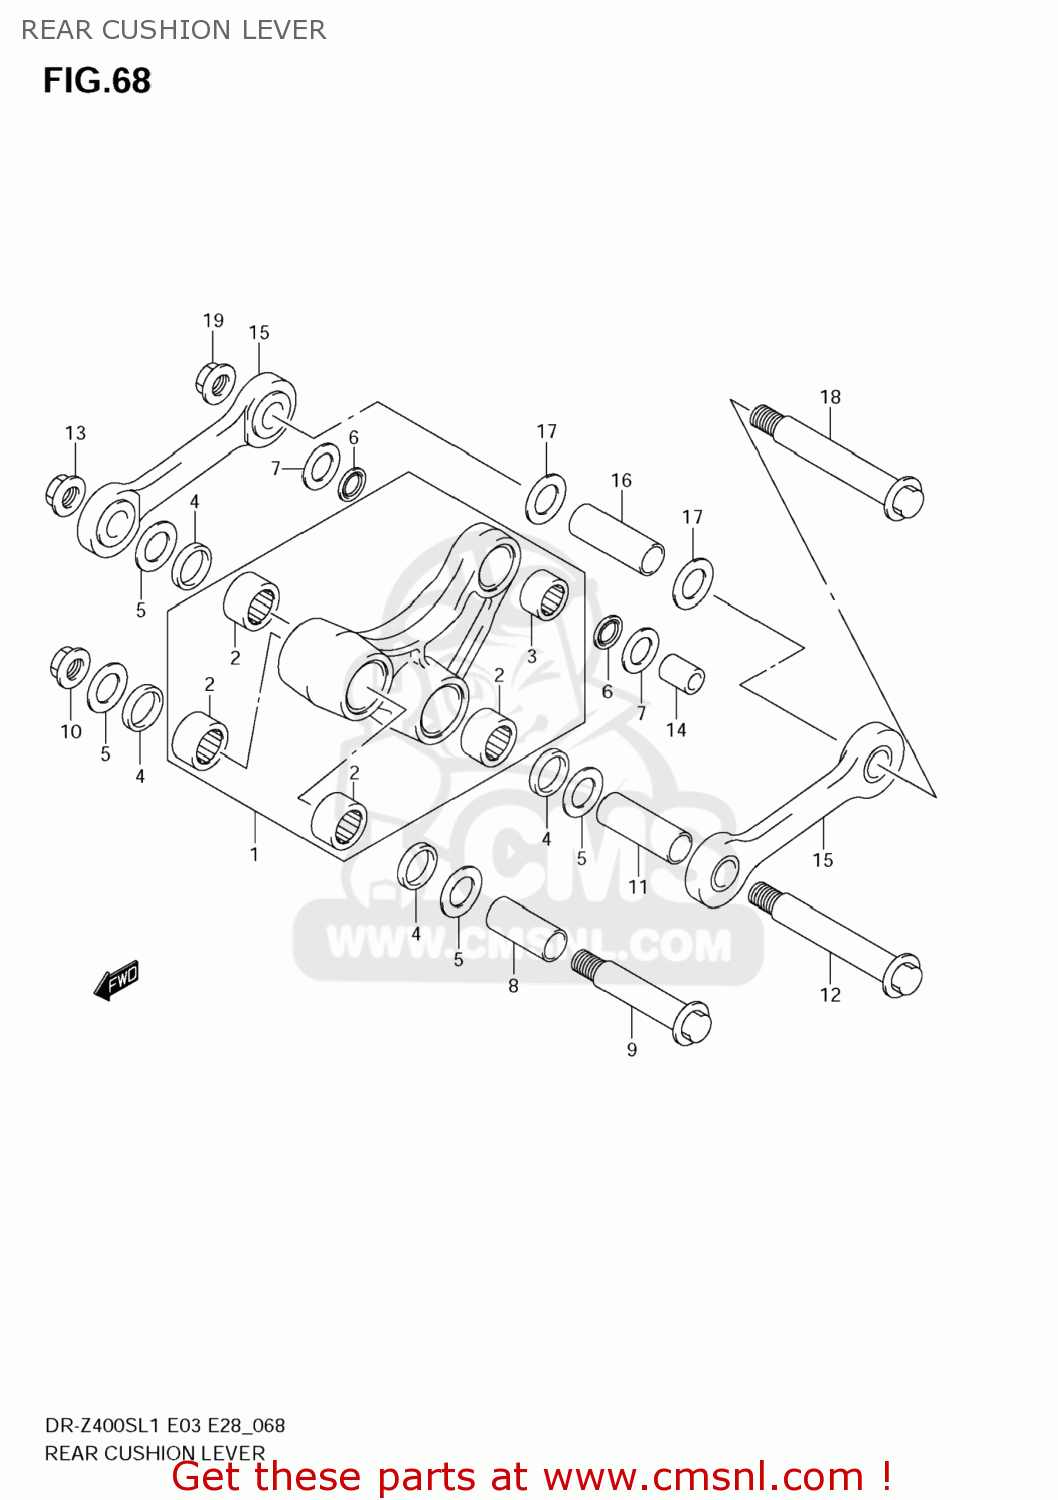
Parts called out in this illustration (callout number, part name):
1	LEVER SET,RR CUSHION
2	BEARING(20X27X15)
3	BEARING(16X22X12)
4	SEAL,CUSHION LEVER DUST
5	WASHER,THRUST SWINGARM RR
6	SEAL,OIL(16X22X2.5)
7	WASHER,THRUST LVR CUSHION RR
8	SPACER,CUSHION LEVER FR
9	BOLT,RR CUSHION LEVER FR
10	NUT
11	SPACER,RR CUSHION
12	BOLT,RR CUSHION
13	NUT
14	SPACER,RR CUSHION LEVER RR
15	ROD SET,RR CUSHION
16	SPACER,RR CUSHION
17	WASHER,THRUST SWINGARM RR
18	BOLT,RR CUSHION
19	NUT
